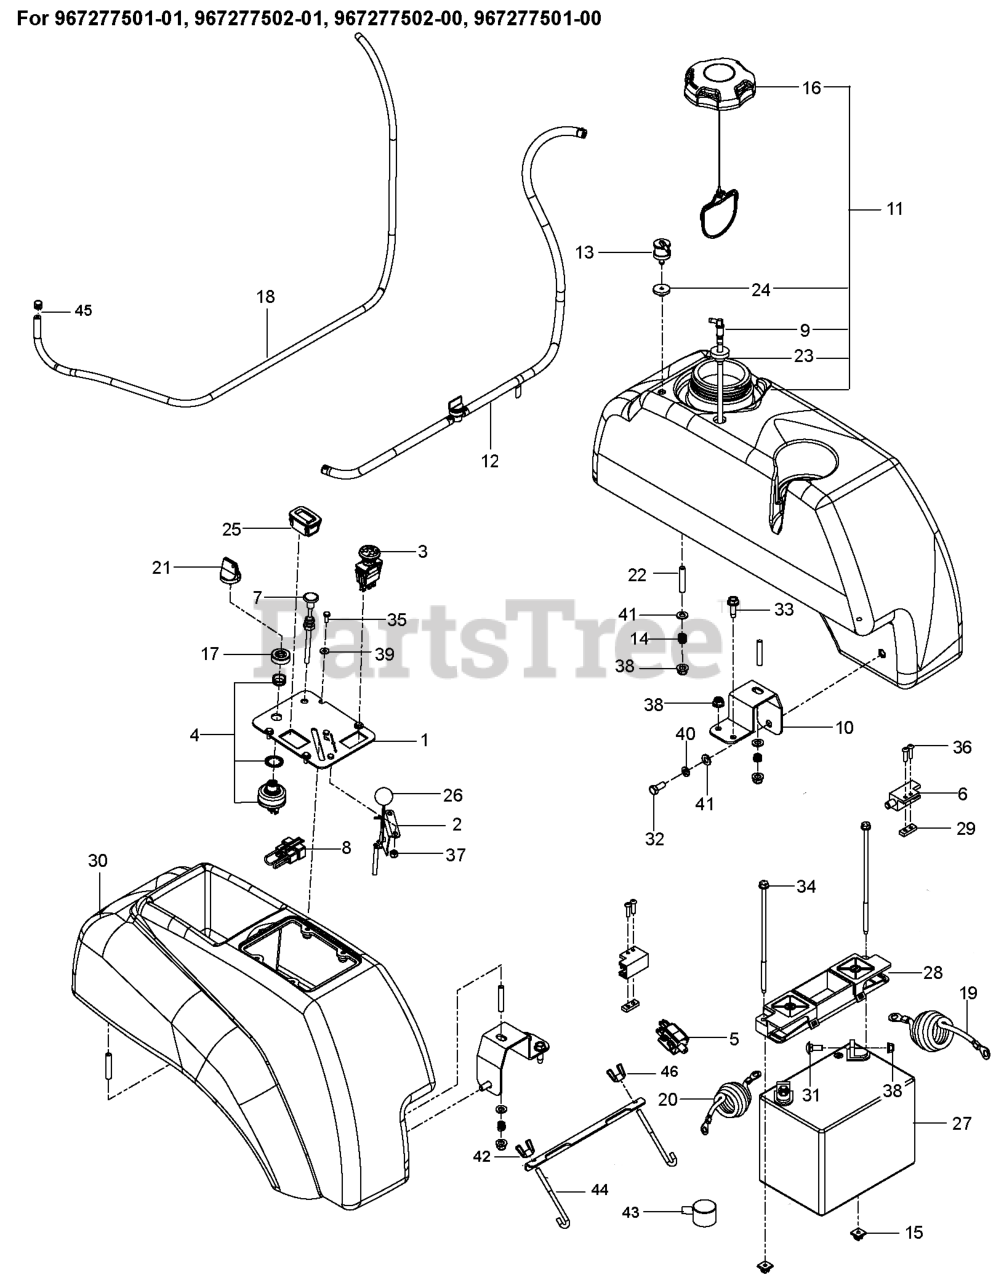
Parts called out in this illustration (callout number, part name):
1	PLATE.CONSOLE.BLACK
2	THROTTLE CABLE
3	RP SWITCH.PTO.TERMINAL.STD.RED
4	SWITCH, IGNITION, INDAK
5	SWITCH, BRAKE 3P
5	SWITCH.INTRLCK.CLUTCH.
6	SWITCH INTERLOCKT
7	CHOKE CABLE
8	PLUG, TIMER
9	FITTING, FUEL
10	SUPPORT.PNT.TANK.FRONT.STAMPED
10	SUPPORT, TANK, BLK
12	FUEL.HOSE.SHUT.OFF.ASM.10".10"
12	FUEL.HOSE.SHUT.OFF.ASM.10".26"
13	VALVE.FUEL.CHECK
14	SPRING
15	PUSH NUT-NYLON
16	CAP, FUEL
17	CAP IGNITION NUT
18	HOSE.3/16".VAPOR.LINE.64"LGTH
18	HOSE.3/16"VAPOR.27"
19	NEG. CABLE, 28"
19	CABLE.GROUND.BATT.MZ.BLACK.39"
20	CABLE.BATT.SOLENOID.MZ.RED.25"
20	POST.CABLE LONG
21	KEY, IGNITION
22	STUD, 5/16C
23	RUBBER GROMMET
24	GROMMET, CHECK VALVE
25	GUAGE.SRVCMNDR.HRMTR.
26	KNOB.ROUND.BALL.BLACK
27	BATTERY, 12 V 330 AMP
28	BATTERY HOLD DOWN
29	PLATE NUT ZTR
29	TAPPED PLATE
30	FENDER CONSOLE
31	BOLT 5/16C X 3/4" CARRIAGE
32	HCS 5/16C X 3/4
32	BOLT.FIN.HEX.5/16-18X3/4
33	RP BLT 5/16-18 X 1 THRD FORM D
33	SCREW
34	BOLT - 1/4-20 X 7.5
35	HCS #10-24 X 1/2
36	SCR #10-24 X .75 SKT HD BLK
37	NUT 10-24 NYLOC
38	RP BOLT 5/16-18 X3/4 ZN/YEL GR
38	5/16-18 NYLOC FLANGE NUT
39	WASHER #10
39	WASHER
40	WASHER.LOCK.HVY.HLCL.SPR.5/16
40	WASH.5/16.SLW.ZD
41	FLAT WASHER 5/16 SAE
41	WASHER
42	BRACKET, BATTERY MOUNT
43	COVER.TERMINAL.BATTERY
44	HOOK, "J"
45	CLAMP, HOSE
46	WING NUT 1/4
